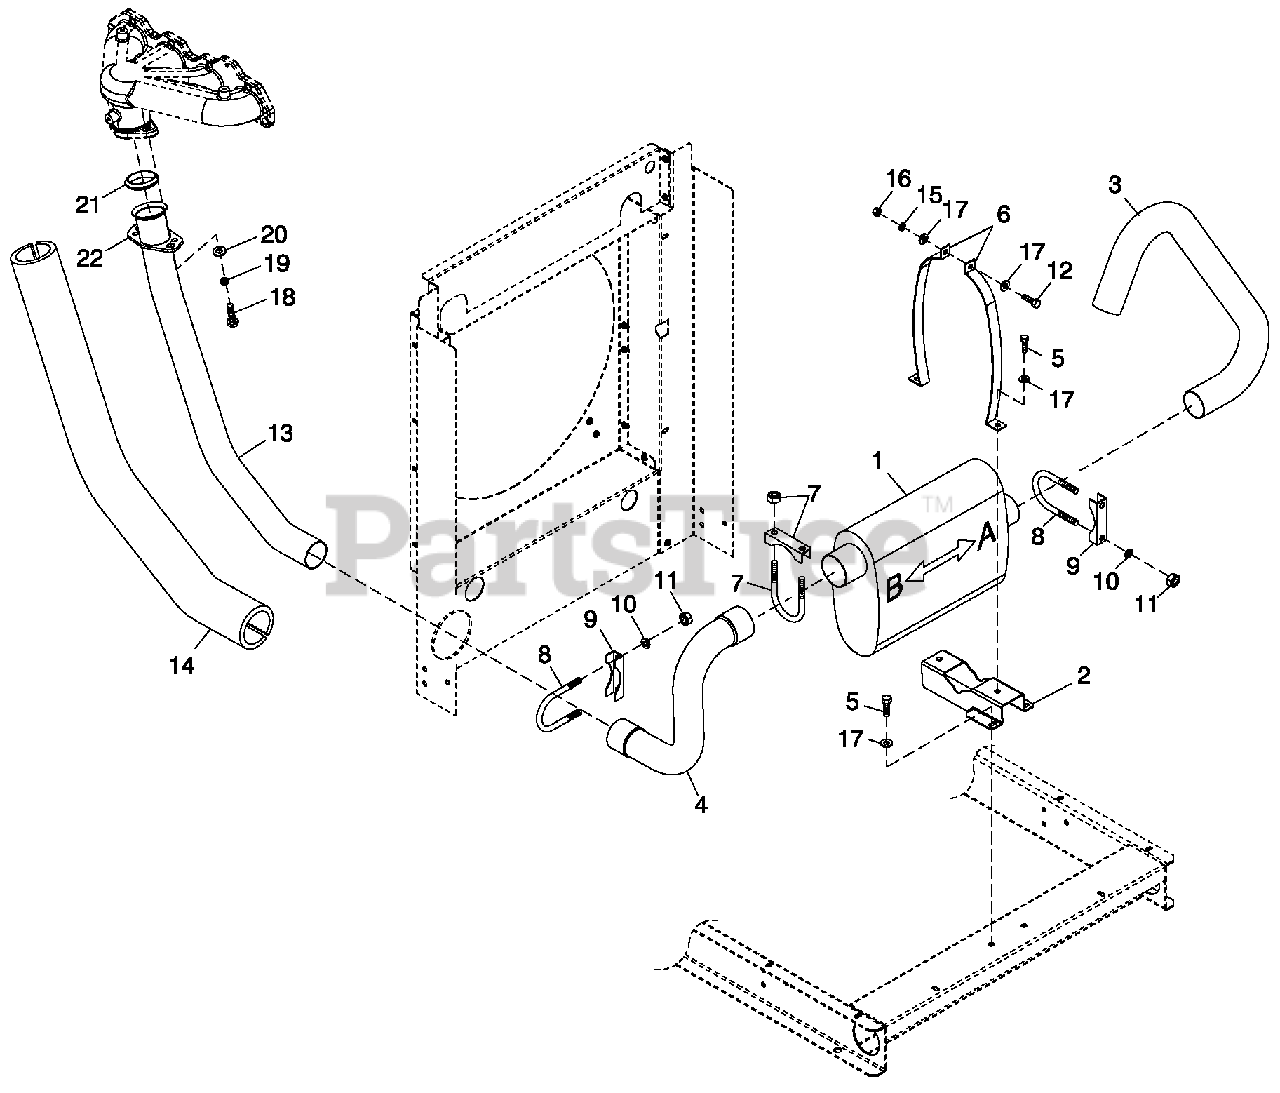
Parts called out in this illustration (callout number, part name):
1	MUFFLER C1
2	MUFFLER SADDLE
3	PIPE EXHAUST OUTLET
4	EXHAUST ELBOW 2.4LG2
5	SCREW HWHTF M6-1.0X16
6	MUFFLER STRAP
7	BOLT U 5/16-18X2-1/4
8	BOLT U 5/16-18X2.09
9	SADDLE 2 INCH
10	WASHER LOCK M8-5/16
11	NUT HEX 5/16-18 STEEL
12	SCREW HHC M6-1.0X 30 G8.8
13	EXHAUST PIPE 2.4LG2
14	EXHAUST BLANKET 700MM LONG
15	WASHER LOCK M6-1/4
16	NUT HEX M6 X 1.0 G8 YEL CHR
17	WASHER FLAT 1/4-M6 ZINC
18	SCREW HHC 3/8-16 X 1-3/4 SS
19	WASHER LOCK 3/8 SS
20	WASHER FLAT 3/8 SS
21	GASKET EXHAUST RING
22	FLANGE EXHAUST 2" PIPE
